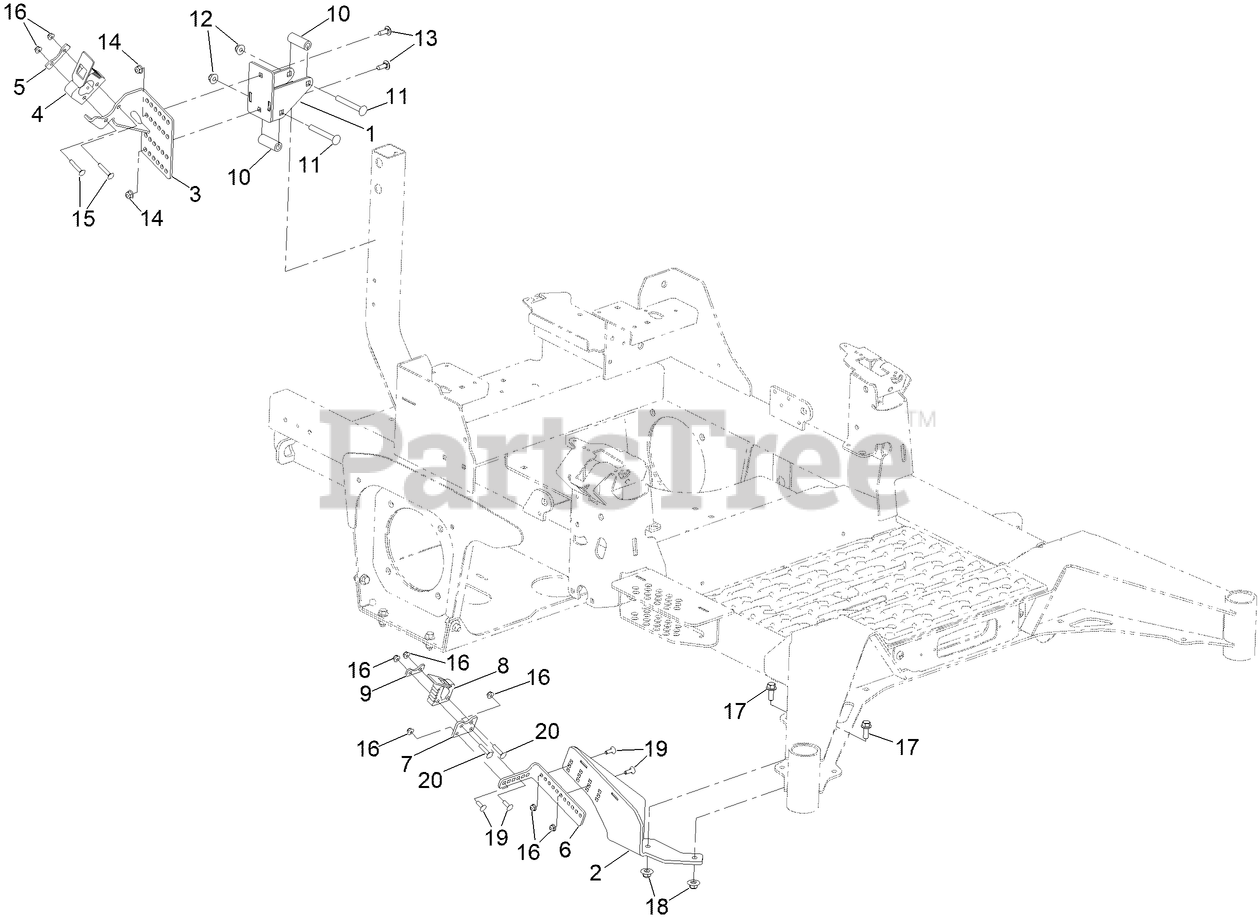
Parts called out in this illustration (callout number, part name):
1	UPPER MOUNT [BLACK]
2	LOWER MOUNT
3	BRACKET-MOUNT, UPPER TRIMMER
4	CLAMP-QUICK FIST, ORIGINAL
5	PLATE-BACKER, LARGE
6	BRACKET-MOUNT, TRIMMER
7	PLATE-MOUNT, QUICK FIST
8	CLAMP-QUICK FIST, MINI
9	PLATE-BACKER, SMALL
10	SPACER-TUBE
11	SCREW-CARR
12	NUT-HF, NI
13	BOLT-CARR
14	NUT-HF, NI
15	SCREW-CARR
16	NUT-HF
17	SCREW-HHF
18	NUT-FLANGE, NI
19	BOLT-CARR
20	SCREW-CARR
